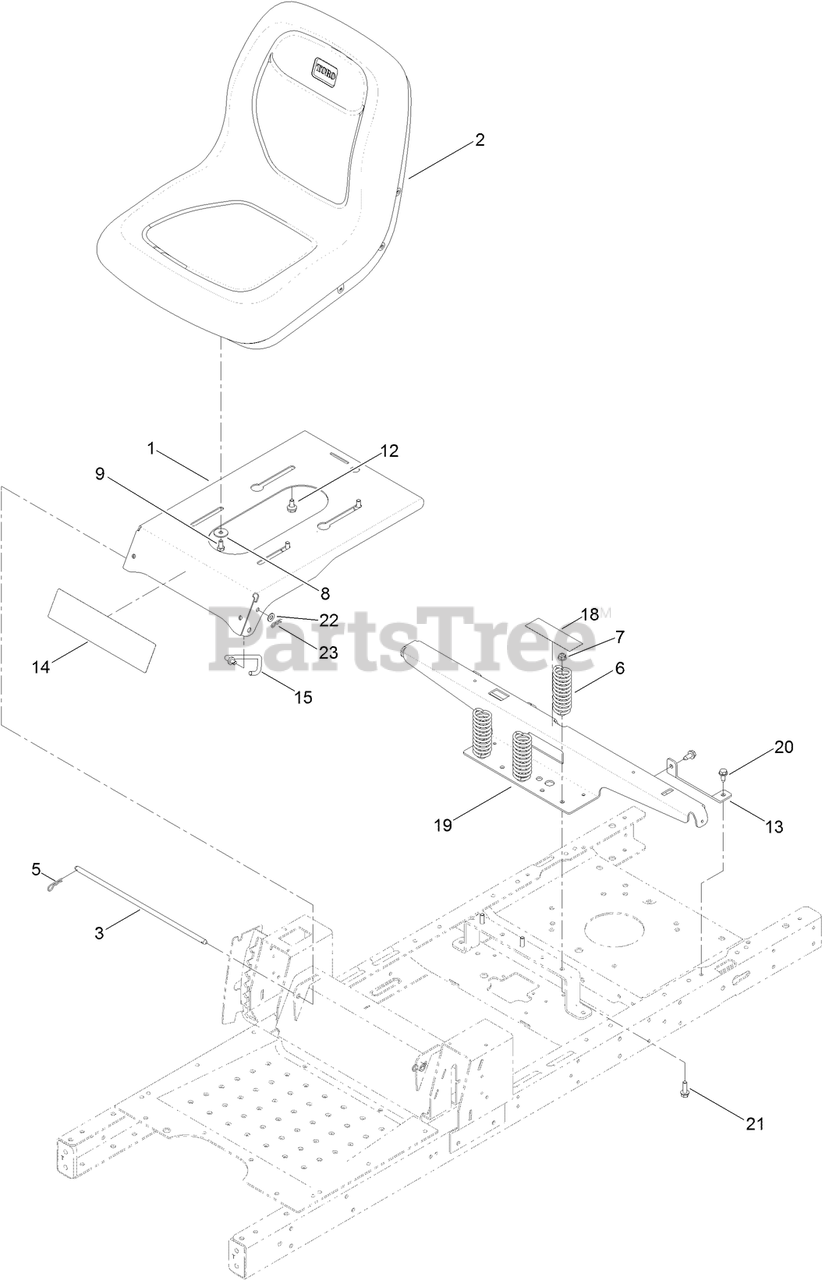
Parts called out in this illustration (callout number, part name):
2	SEAT-18 INCH
3	ROD-PIVOT, NARROW
5	PIN-COTTER
6	SPRING-COMPRESSION
7	NUT-HF, NI
8	WASHER-PIVOT
9	SCREW-HH
12	BOLT-SHOULDER,HFH
13	SUPPORT-TANK, REAR
14	DECAL-TIMECUTTER
15	STOP-SEAT
18	DECAL-SERVICE, CE
19	SUPPORT-POD
20	SCREW-HWHTF
21	SCREW-HHF
22	WASHER-PLAIN
